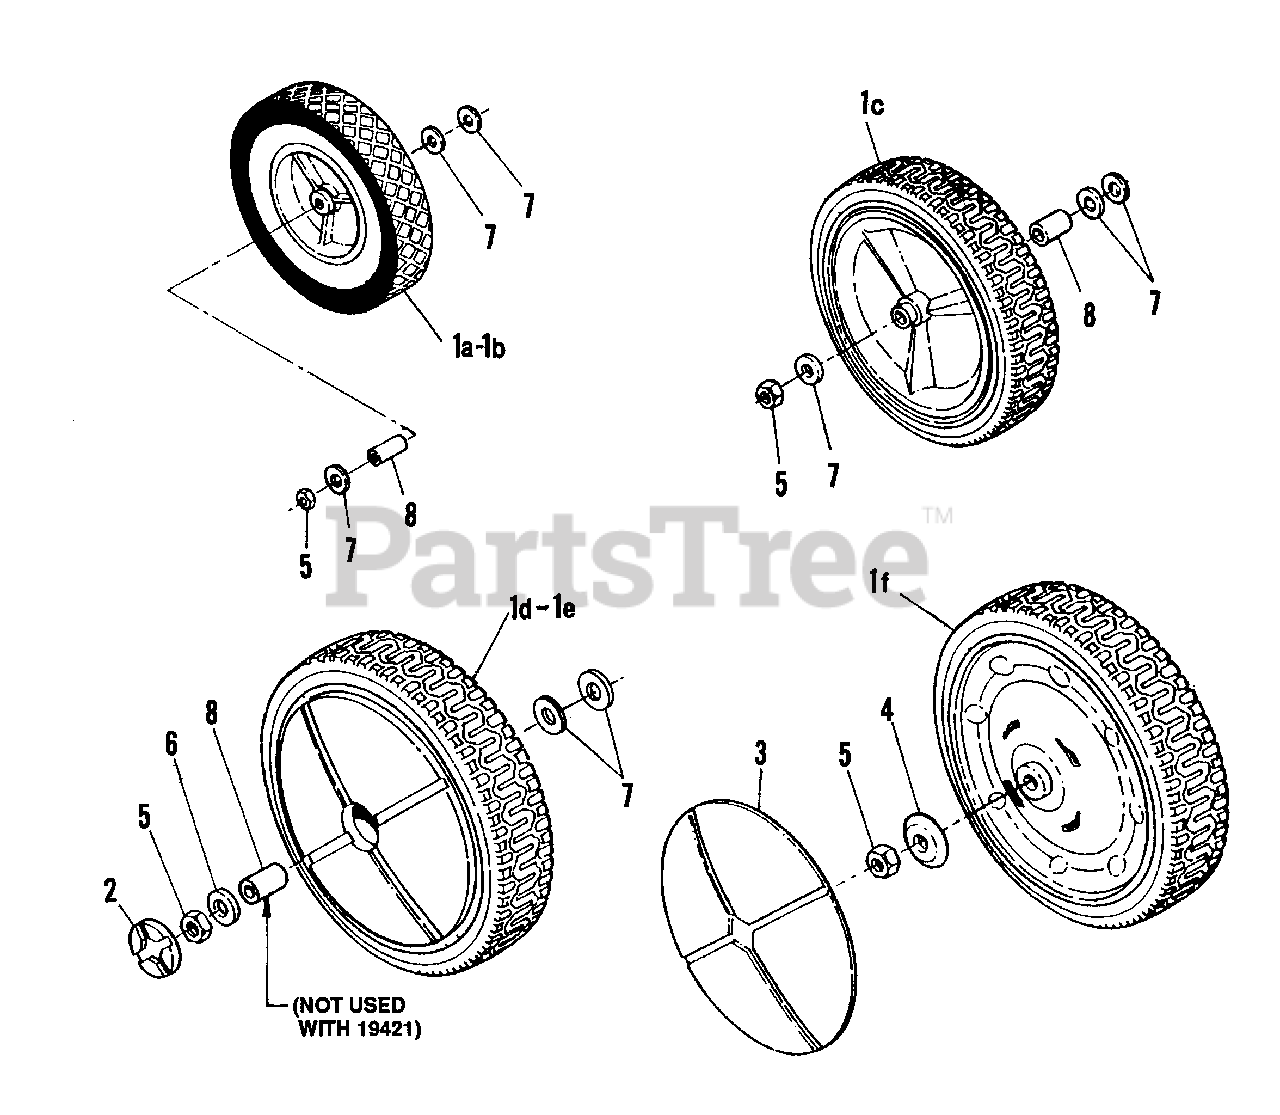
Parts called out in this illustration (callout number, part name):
1A	WHEEL, 9 x 1.75 - Plastic
1B	WHEEL, 9 x 1.75 - Plastic
1C	WHEEL, 9 x 2.00 - Plastic
1D	WHEEL, 9 x 2.00 - Plastic
1E	WHEEL, 9 x 2.00 - Plastic
1F	WHEEL, 9 x 2.00 - Steel
2	PLUG, Wheel
3	WHEEL COVER, 9" Steel
4	HUB CAP
5	NUT, 7/16 - 20 Hex Thin
6	WASHER, 7/16" ID SAE
7	WASHER, 1" O.D. Flat
8	AXLE BUSHING
